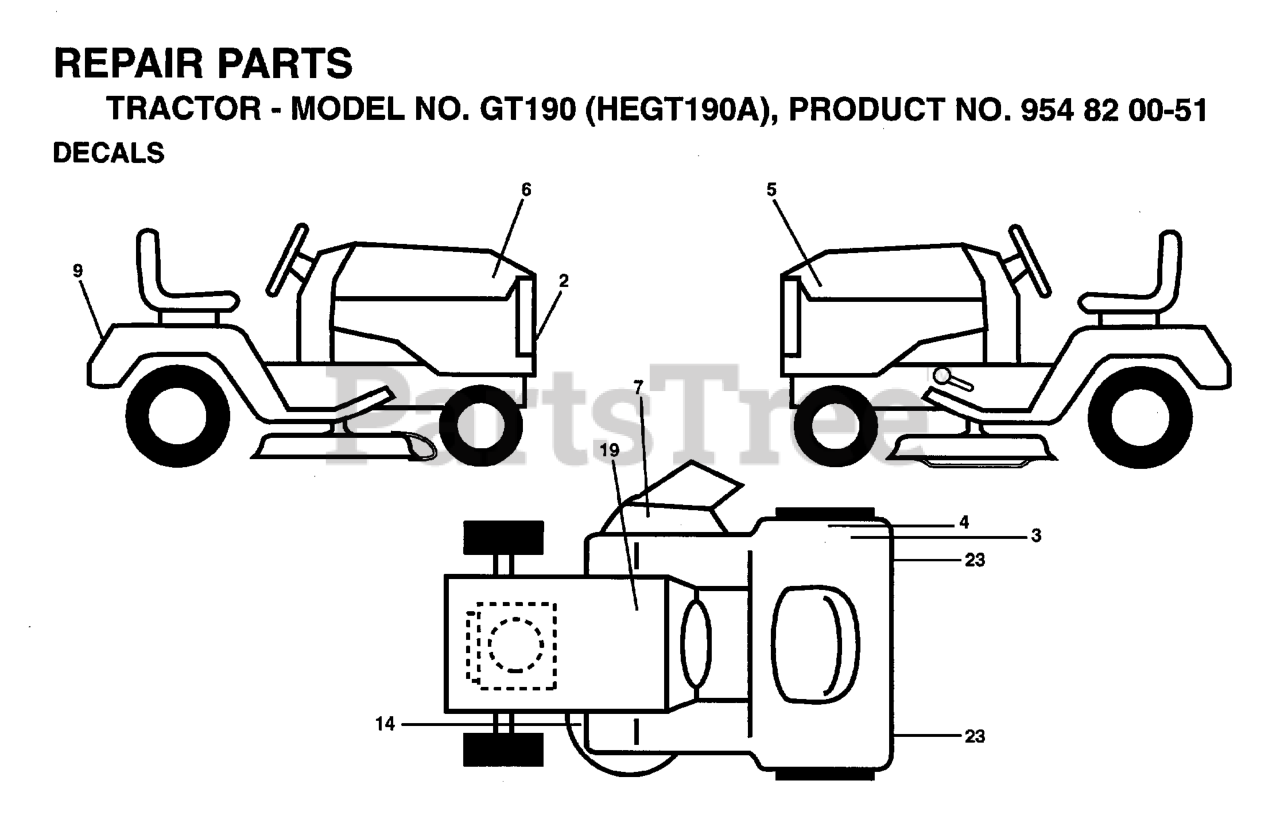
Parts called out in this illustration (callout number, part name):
2	DECAL.GRILLE.HUSQ
4	DECAL EUROPE STANDARD CE
7	DECAL MOWER CUT/FINGER
8	DECAL PARK BRAKE
9	Decal, Fender
10	DECAL READ OWNER'S MAN SYMS
19	DECAL, BATTERY DANGER
23	REFLECTOR-TAIL YT
